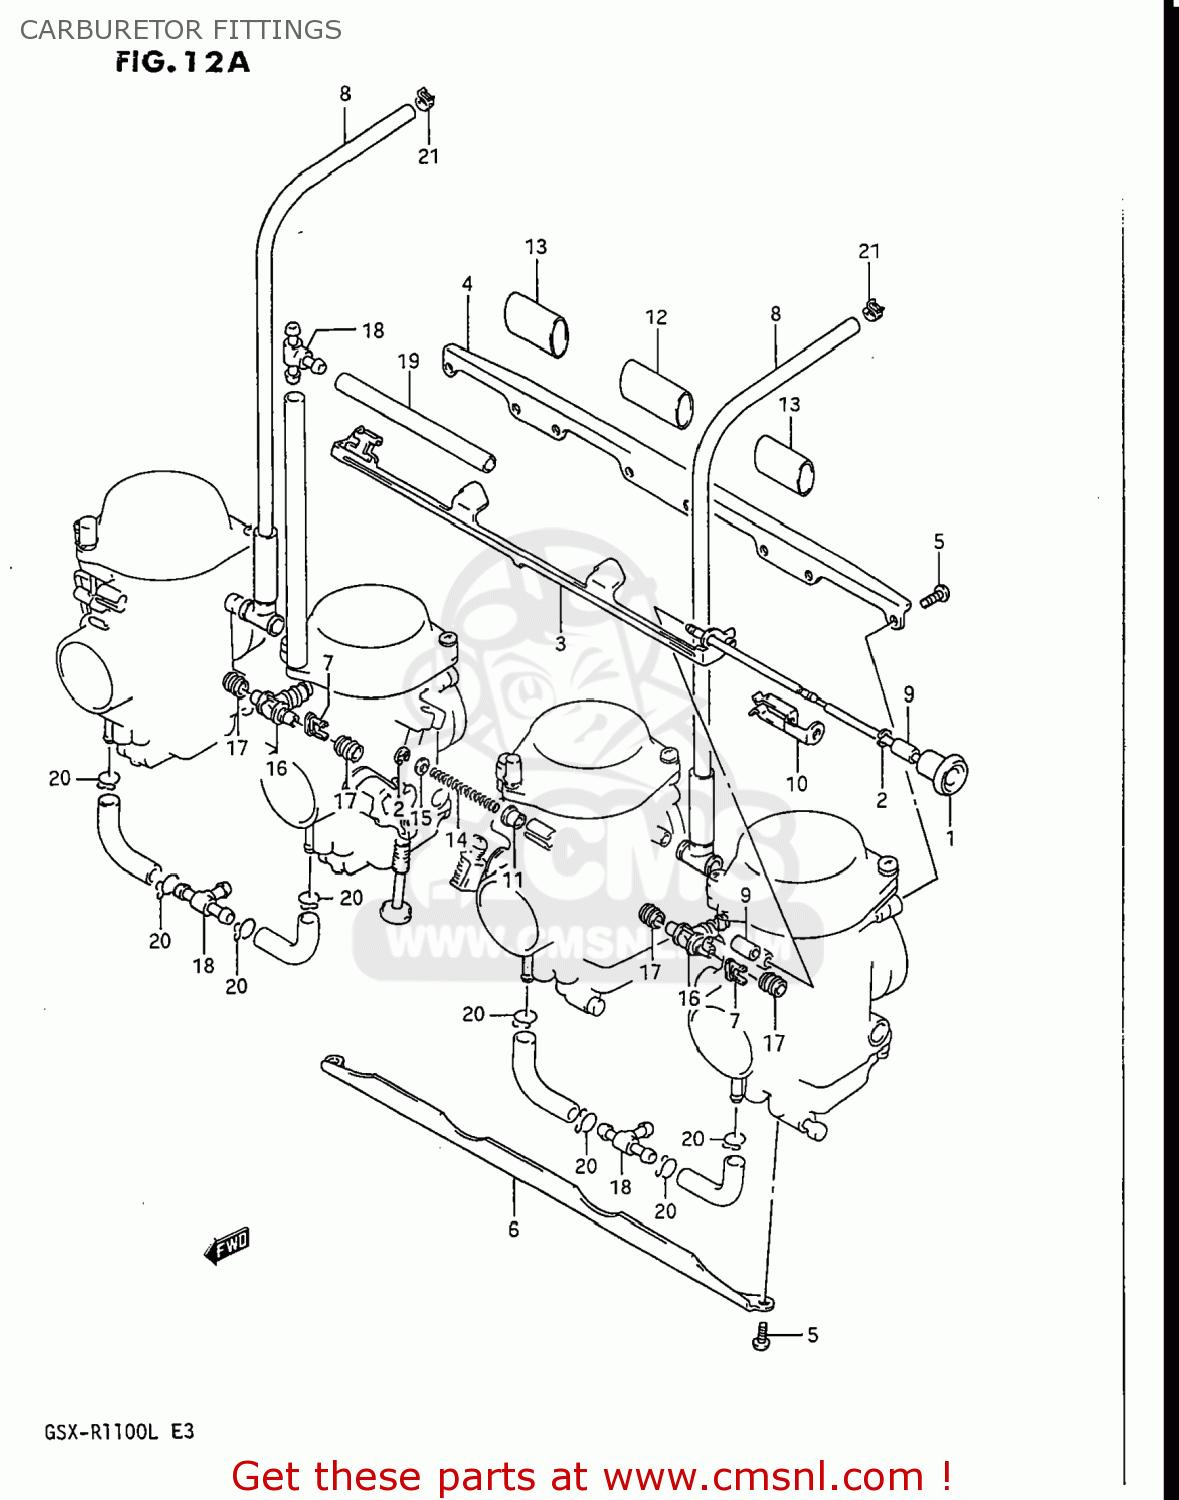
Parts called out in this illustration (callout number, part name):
1	SHAFT ASSY,STARTER
2	E RING
3	LEVER
4	PLATE
5	SCREW
6	PLATE
7	HOLDER
8	HOSE
9	SPACER
10	PLATE
11	RING
12	HOSE
13	HOSE
14	SPRING
15	WASHER
16	NIPPLE
17	SEAL
18	NIPPLE
19	HOSE
20	CLIP
21	CLIP
